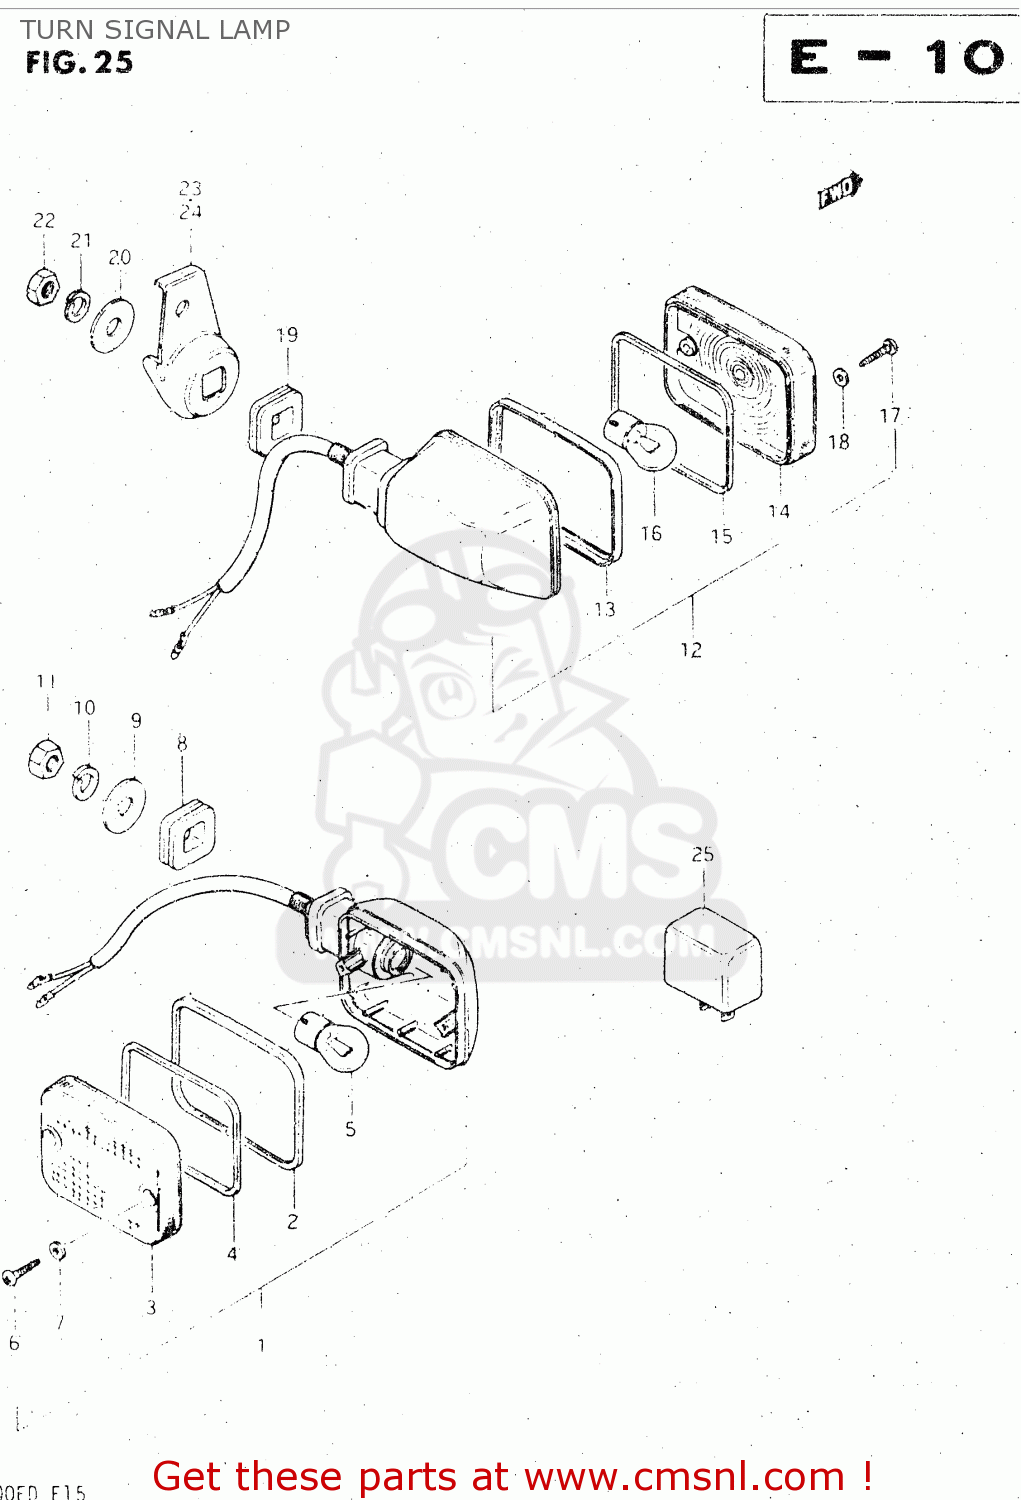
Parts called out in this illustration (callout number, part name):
1	LAMP ASSY,FR T
2	RIM
3	LENS
4	GASKET (NAS)
5	BULB(12V21W)
6	SCREW
7	GASKET (NAS)
8	CUSHION
9	WASHER (10.5X30X2.3)
10	LOCK WASHER
11	NUT
12	LAMP ASSY,RR T
13	RIM
14	LENS
15	GASKET (NAS)
16	BULB(12V21W)
17	SCREW
18	GASKET (NAS)
19	CUSHION
20	WASHER (10.5X30X2.3)
21	LOCK WASHER
22	NUT
23	BRACKET,REAR TURN SIGNAL
24	BRACKET,REAR TURN SIGNAL
25	RELAY,TURN SIGNAL
